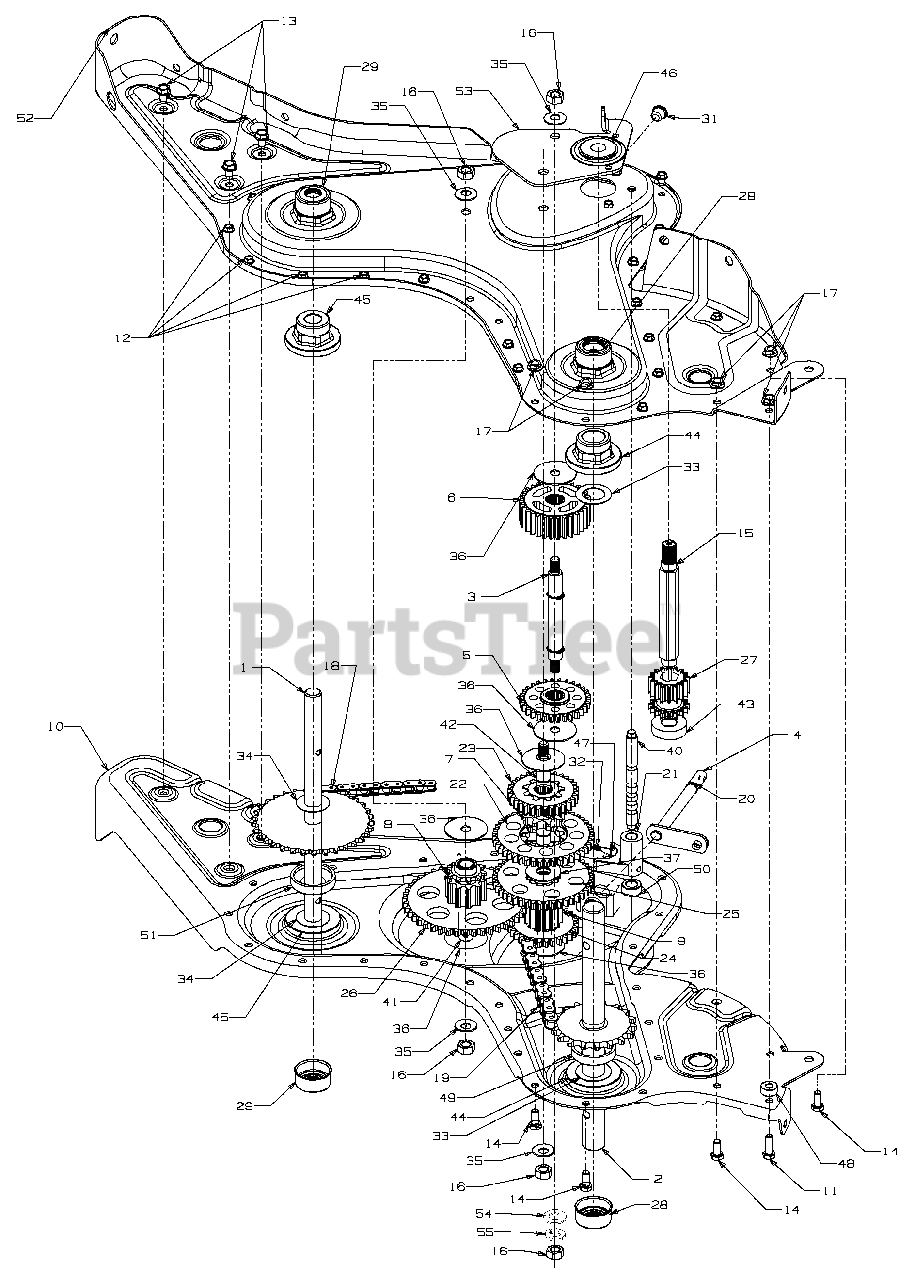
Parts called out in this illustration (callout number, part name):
1	Wheel Shaft Ass'y: 33T
2	Tine Shaft Ass'y: 18T
3	Jack Shaft Ass'y
4	Input Shaft Ass'y
5	Rev. Idler Gear Ass'y: 30T
6	Ftine Idler Gear Ass'y: 30T
7	Tine Input Sprocket Ass'y: 9T
8	Wheel Input Sprocket Ass'y: 10T
9	Gear Ass'y: 11T
11	Hex Bolt 5/16-18 x 1" Lg.
12	Hex S-Tap Scr. 1/4- 20 x.5"
13	Hex S-Tap Scr. 5/16-18 x.625"
14	Hex Bolt 5/16-18 x.75"
15	Input Shaft
16	Hex Nut 7/16-20
17	Flange Nut 5/16-18
18	#420 Chain 1/2 Pitch x 50 Links
19	#50 Chain 5/8 Pitch x 54 Links
20	Snap Ring
21	Shifting Fork
22	Spur Gear 44T
23	Spur Gear 30T
24	Spur Gear 30T
25	Spur Gear 44T
26	Spur Gear 44T
27	Spur Gear 16T
28	Seal 1.0 Shaft
29	Seal .75 Shaft
31	Taper Cap Ring
32	Compression Spring .50" Lg.
33	Thrust Wash. 1.03" I.D. x 1.62"
34	Fl-Wash .76" I.D. X. 1.5" O.D.
35	Bell-Wash .45" I.D. X. 1.0"
36	Thrust Wash .445 x 1.92 x.060
37	Fl-Wash .635" I.D. x 1.59 O.D.
40	Detent Shaft 1/2" Dia.
41	Jack Shaft .625 x 2.385
42	Jack Shaft .625 x 5.0
43	Ball Bearing
44	Flange Bearing 1.0 x 2.5 x 1.38
45	Flange Bearing .75 x 2.5 x 1.38
46	Ball Bearing .6692 x 5745 x.466
47	Detent Ball .250
48	Spacer .315
49	Spacer 1.0 I.D x 2.0 O.D. x .440
50	Spacer .505 I.D. x .88 O.D. x .440
51	Spacer .75 x 2.0 x .50
53	Gear Positioner Bracket
54	Flat Washer, .474 ID x .879 OD
55	Lock Washer, 7/16
